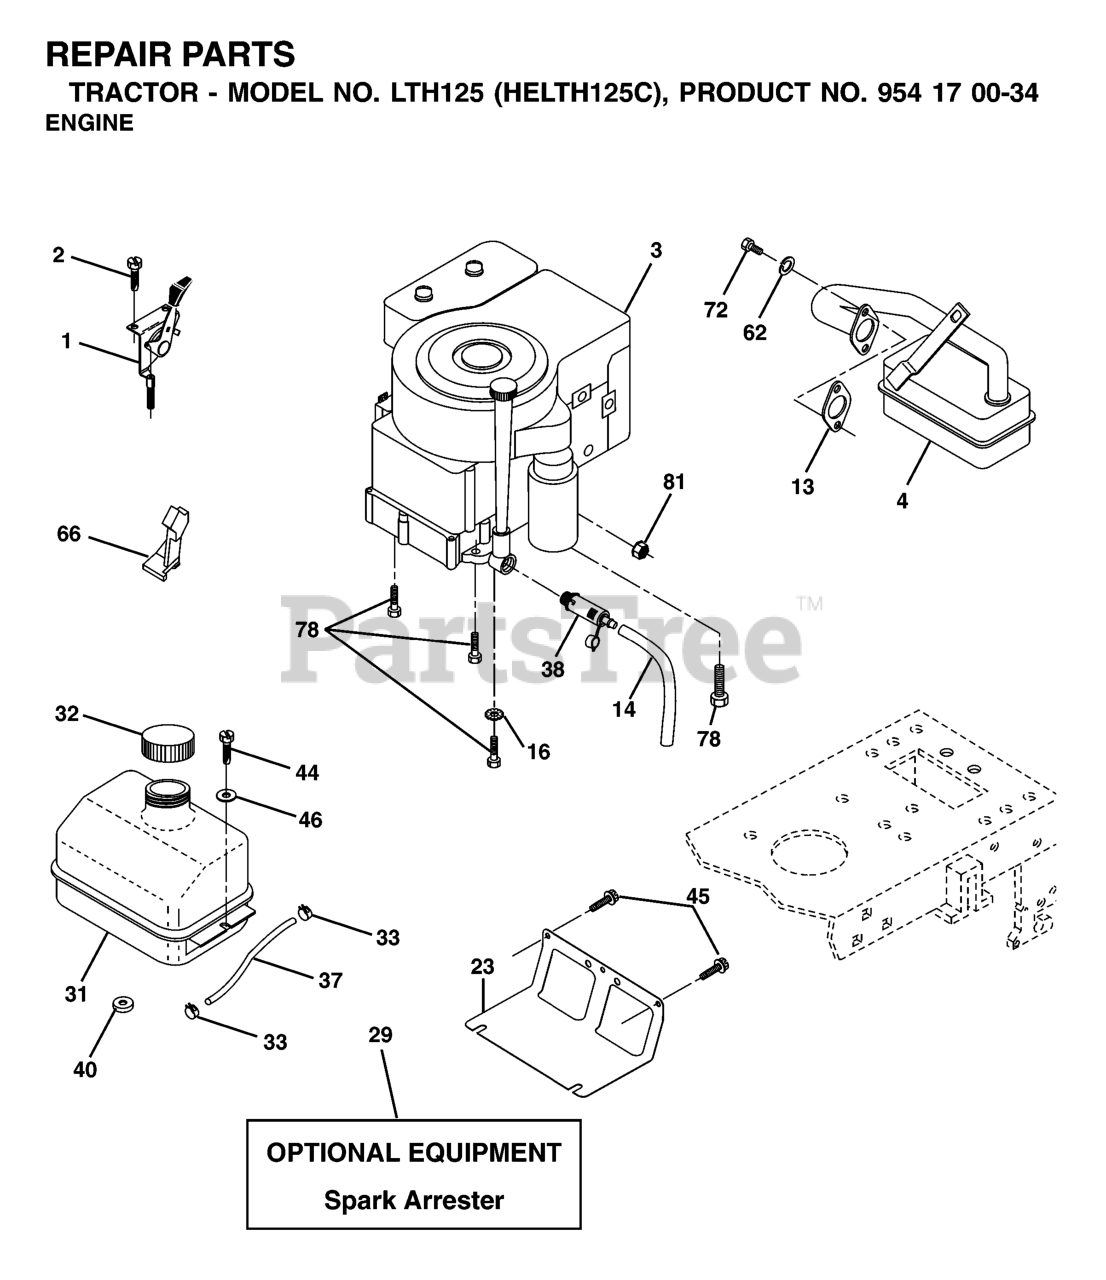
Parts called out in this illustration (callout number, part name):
1	THROTTLE.CONTROL.CABLE.BLACK
2	SCREW
4	MUFFLER.SINGLE.B&S.10-12HP
13	REPL BY 532 27 22-93
14	TUBE, DRAIN OIL ASM.
16	LOCKWASHER
23	SHIELD.BROWNING.DBR.GUARD
29	KIT.SPARK ARRESTOR 794945 B&S
31	TANK FUEL LT
32	FUEL CAP
33	HOSE CLAMP
37	LINE.FUEL.20
38	PLUG, OIL DRAIN EASY
40	BUSHING.SNAP.NYL.BLK.
44	SCREW HEXWSHR 1/4-20X3/4
45	SCREW, 3/8-16X3/4
62	WASHER.LOCK.HVY.HLCL.SPR.5/16
66	STOP THROTTLE
72	SCREW
78	SCREW.3/8-16
81	NUT
